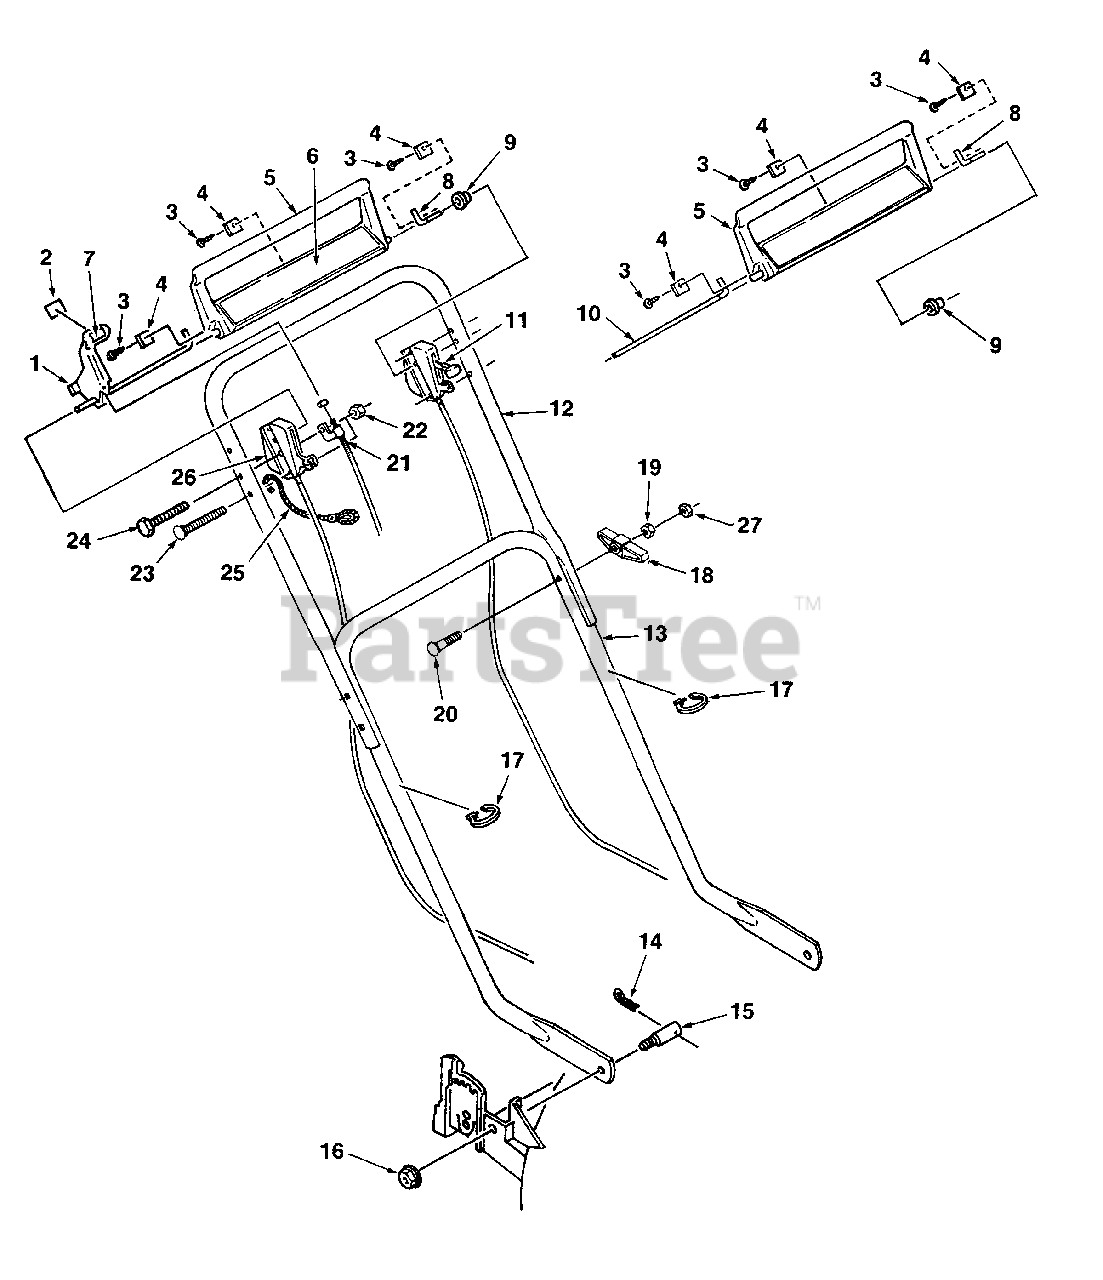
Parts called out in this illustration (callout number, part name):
1	TRACTION LEVER
2	DECAL- Traction lever
3	SCREW- Truss hd.
4	CLAMP- Pivot shaft
5	BAIL- Brake control
6	DECAL- Brake bail
7	DECAL- Product indentification
8	SHAFT- Pivot
9	SPACER- Bail
10	SHAFT- Pivot
11	CONTROL- Throttle
12	HANDLE- Upper
13	HANDLE- Lower
14	PIN- Hair
16	NUT- Flange
17	CLAMP- Cable single
18	KNOB- Handle
19	NUT- Hex
20	BOLT- Sq. neck
21	CABLE- Traction control
23	BOLT- Sq. neck
24	SCREW- Hex hd.
25	ROPE- Restraint
26	CONTROL- Manual start
27	NUT- Hex lock
